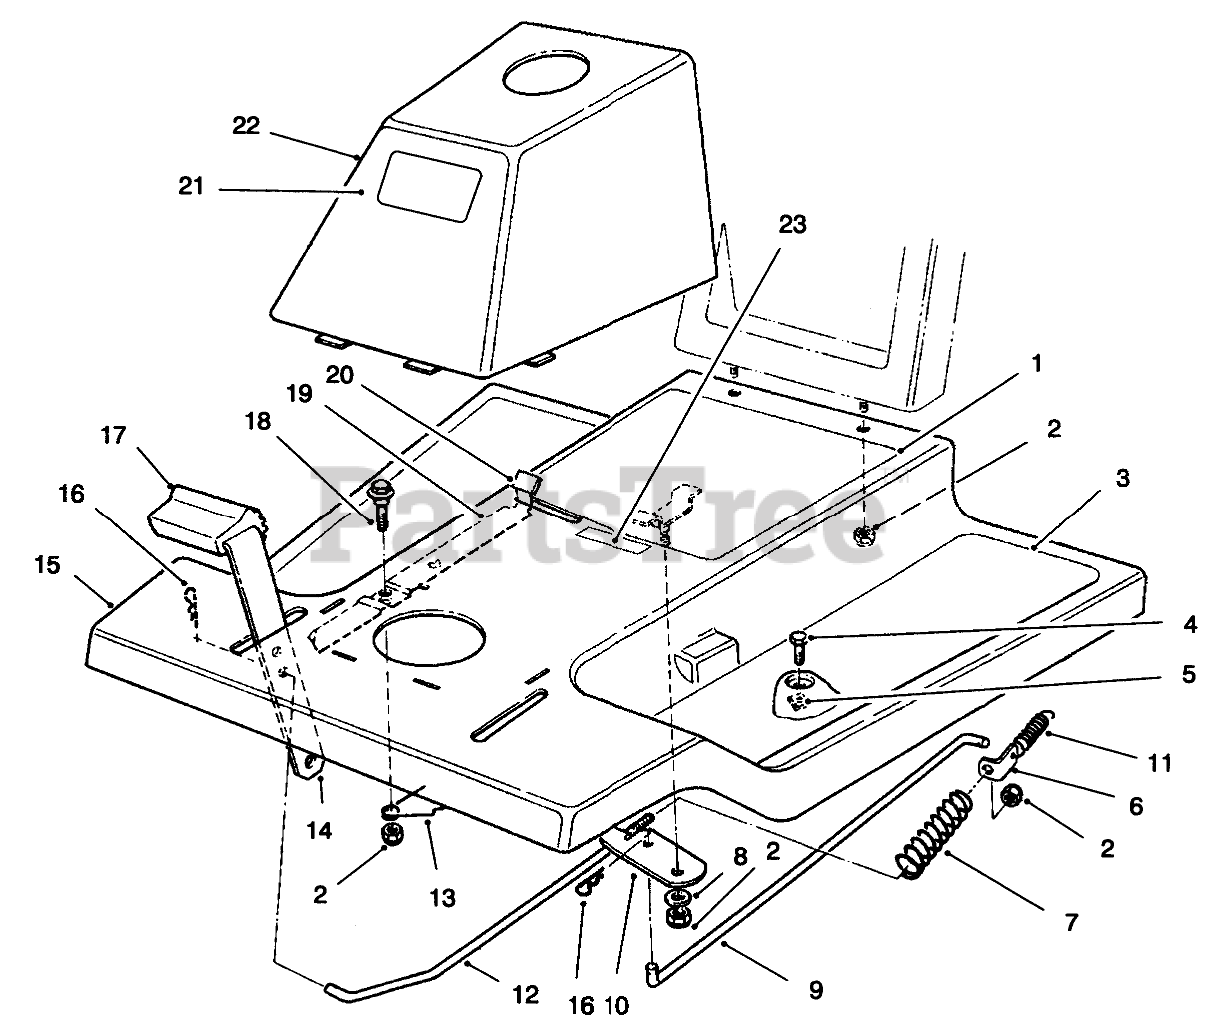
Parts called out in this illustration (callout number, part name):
1	DECAL - INSTRUCTION
2	NUT-LOCK, NI
3	TREAD-FOOT
4	SCREW-HH
5	NUT-TINNERMAN
6	BRACKET-BRAKE RETURN
7	SPRING-TRACTION BRAKE
8	WASHER-PIVOT
9	ROD-TRANS BRAKE
10	LEVER-BRAKE
11	SPRING-IDLER
12	ROD-FRONT BRAKE
13	SPRING-PARKING BRAKE
15	Body W.A.-Front
16	PIN-COTTER
17	PAD-PEDAL
18	SCREW-SHOULDER
19	PARKING BRAKE (BLACK)
20	TIP-PARKING BRAKE
21	DECAL
22	Tower (Incl. Ref. #21)
23	DECAL - PARKING BRAKE
